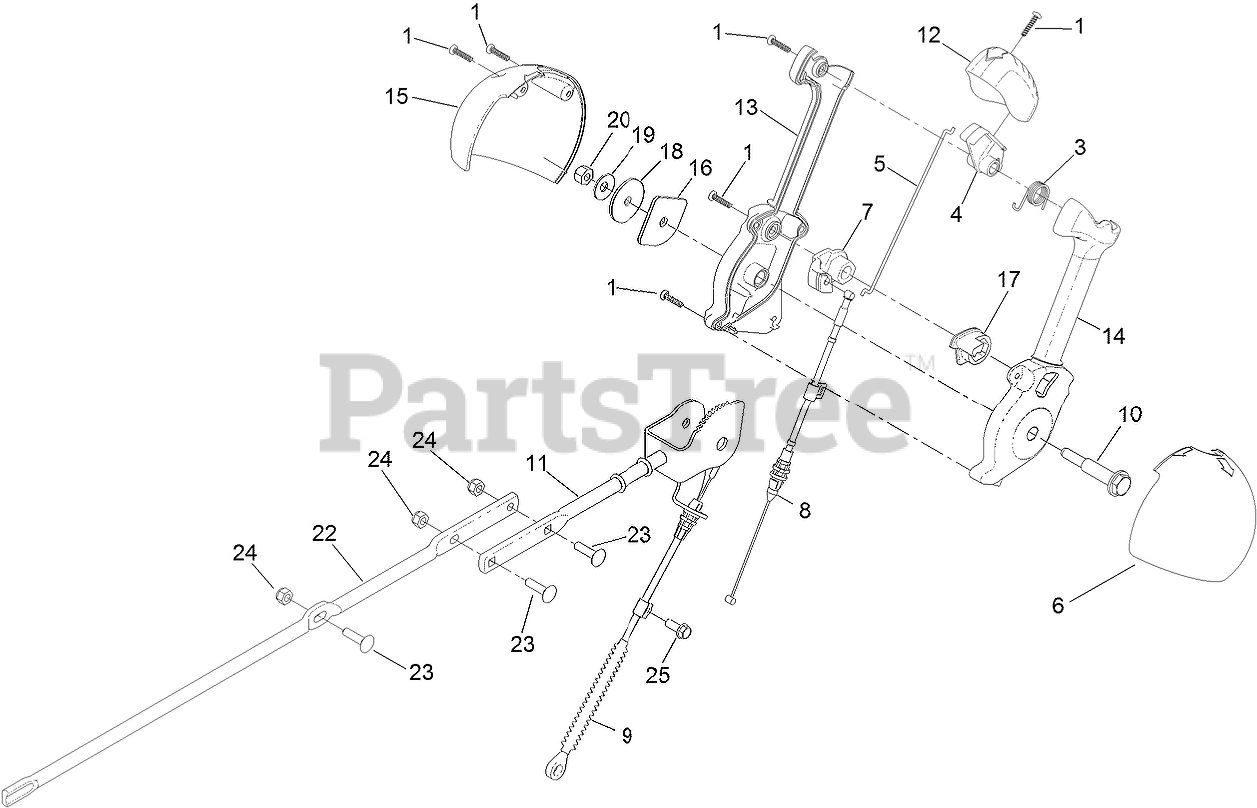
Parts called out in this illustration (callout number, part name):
1	SCREW-PPH
3	SPRING-TORSION
4	TRIGGER-LATCH
5	LINK-LATCH
6	COVER-LEVER, CHUTE (LH)
7	LEVER-CABLE, DEFLECTOR
8	CABLE-RELEASE, CHUTE
9	CABLE-CONTROL, DEFLECTOR
10	SCREW-SHOULDER
11	CHUTE CONTROL ROD
12	CAP-LEVER
13	LEVER-CONTROL, CHUTE (RH)
14	LEVER-CONTROL, CHUTE (LH)
15	COVER-LEVER, CHUTE (RH)
16	PLATE-FRICTION
17	PAWL-LATCH
18	WASHER-NYLON
19	WASHER-BELLEVILLE
20	NUT-HEX
22	ROD-CHUTE
23	BOLT-CARR
24	NUT-HEX
25	SCREW-HWH
